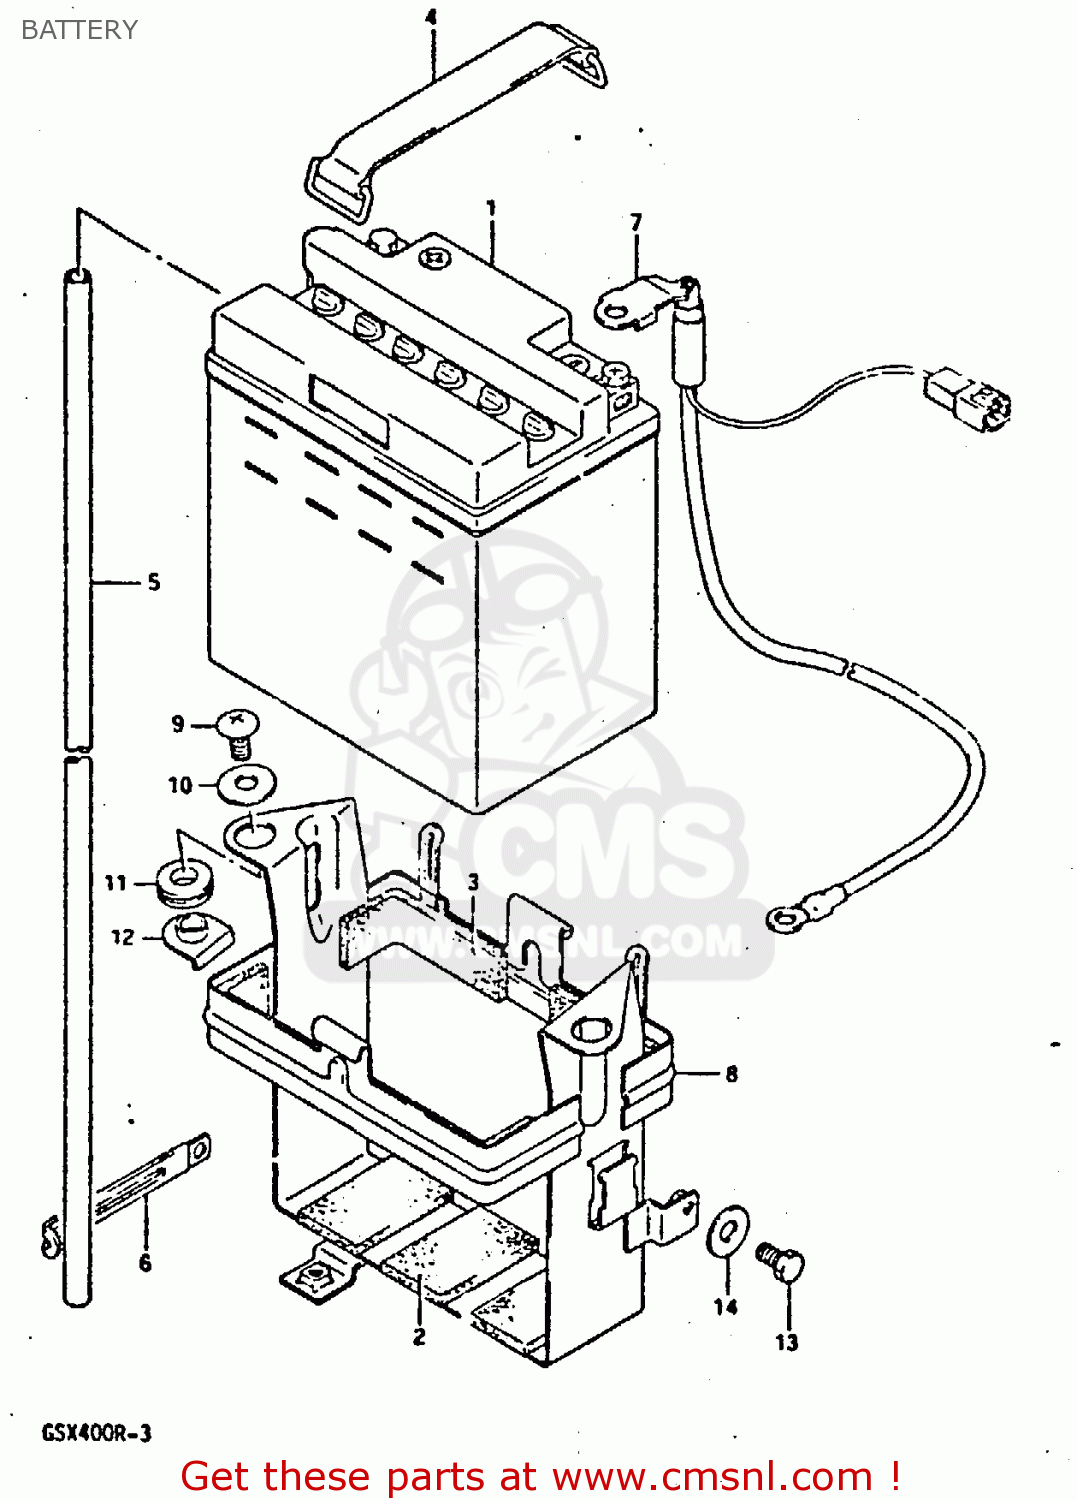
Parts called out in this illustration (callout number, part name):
2	PROTECTOR(170X95X3.0)
3	PROTECTOR,20X9
4	BAND
5	HOSE,BATTERY EXHAUST
6	CLAMP
7	WIRE,BATTERY MINUS LEAD
9	SCREW, CENTER
10	WASHER
11	CUSHION
12	WASHER
13	BOLT
14	WASHER (6.5X18X1.6)
